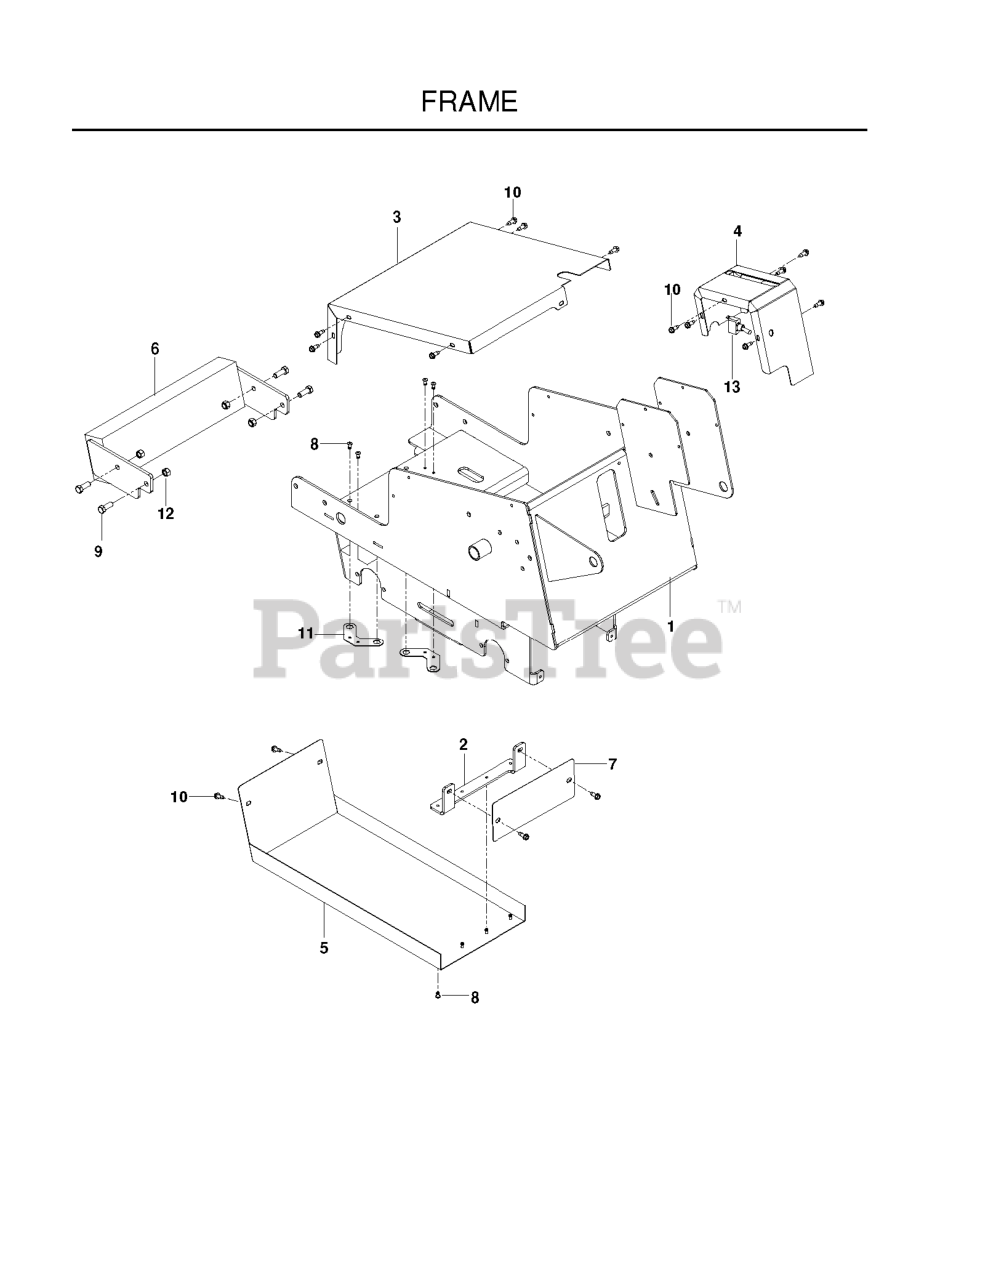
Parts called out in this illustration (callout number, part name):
1	CHASSIS - ORANGE
2	END BRACKET, ORANGE
3	COVER - TOP, ORANGE
4	COVER, SHIFT, ORANGE
5	BELLY PAN, ORANGE
6	WLDMT - WEIGHT, BLACK
7	SHIELD - CE REAR PULLEY
8	RIVERT, 3/16, STAVEX
9	HCS 3/8-16X1.GRD.5.ZD
10	SCREW 1/4 X 5/8
11	NUT PLATE, BLACK
12	NUT 3/8-16 NYLOC
13	SWITCH, TOGGLE, GROUNDING
